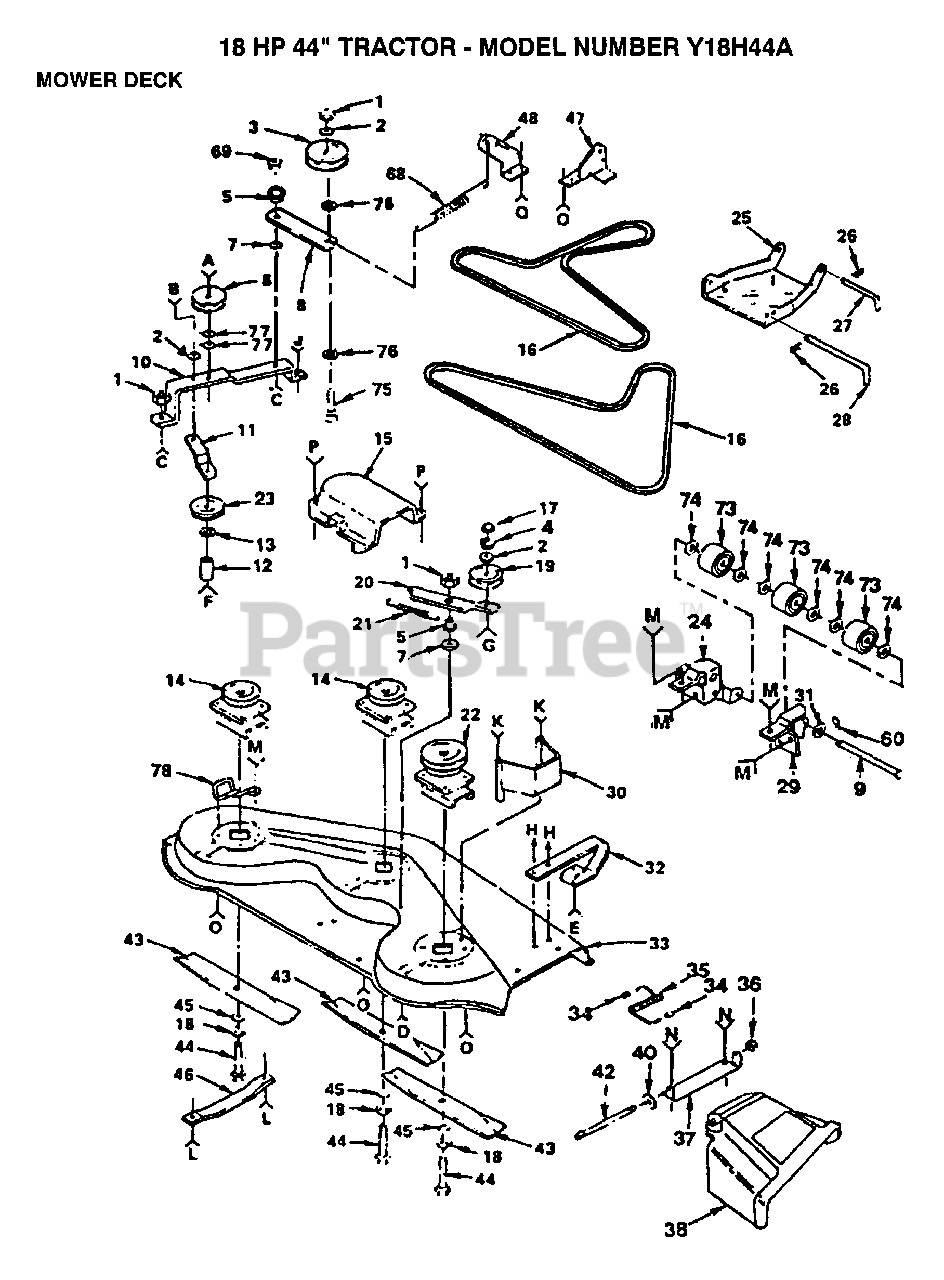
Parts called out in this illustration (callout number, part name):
2	WASHER
3	PULLEY IDLER
4	LOCKWASHER
5	SPACER RETAINER
7	"WASHER, WEAR LT"
8	ARM IDLER
9	PIVOT PIN T
10	"SUPPORT YT, BAR"
11	BRACE-IDLER YT
12	SPACER
13	WASHER
15	GUARD YT
16	BELT-V.79.1.MWR
17	NUT.HEX.3/8-16UNC
19	IDLER.FLAT.GTV
20	ARM-IDLER YT
23	IDLER-FLAT T
24	BRACKET LH YTH
25	LINK.PARALLEL
26	SPRING.RETAINER
27	"ROD, FRT. PARAL T"
28	HINGE PIN T
29	BRACKET RH YTH
30	GUARD BELT HYT
34	CAP-SLEEVE LT
36	NUT PUSH M
38	DEFLECTOR SHIELD
40	WASHER
42	ROD-HINGE T
44	BOLT.3/8-24X1-1/2
45	WASHER
47	BRKT SUSP REAR RH
48	BRKT SUSP REAR LH
60	COTTER PIN
68	"SPRING.EXT.8.5"""
73	ROLLER T
74	WASHER T
75	BOLT
76	WASHER
77	WASHER
78	BELT RETIANER
